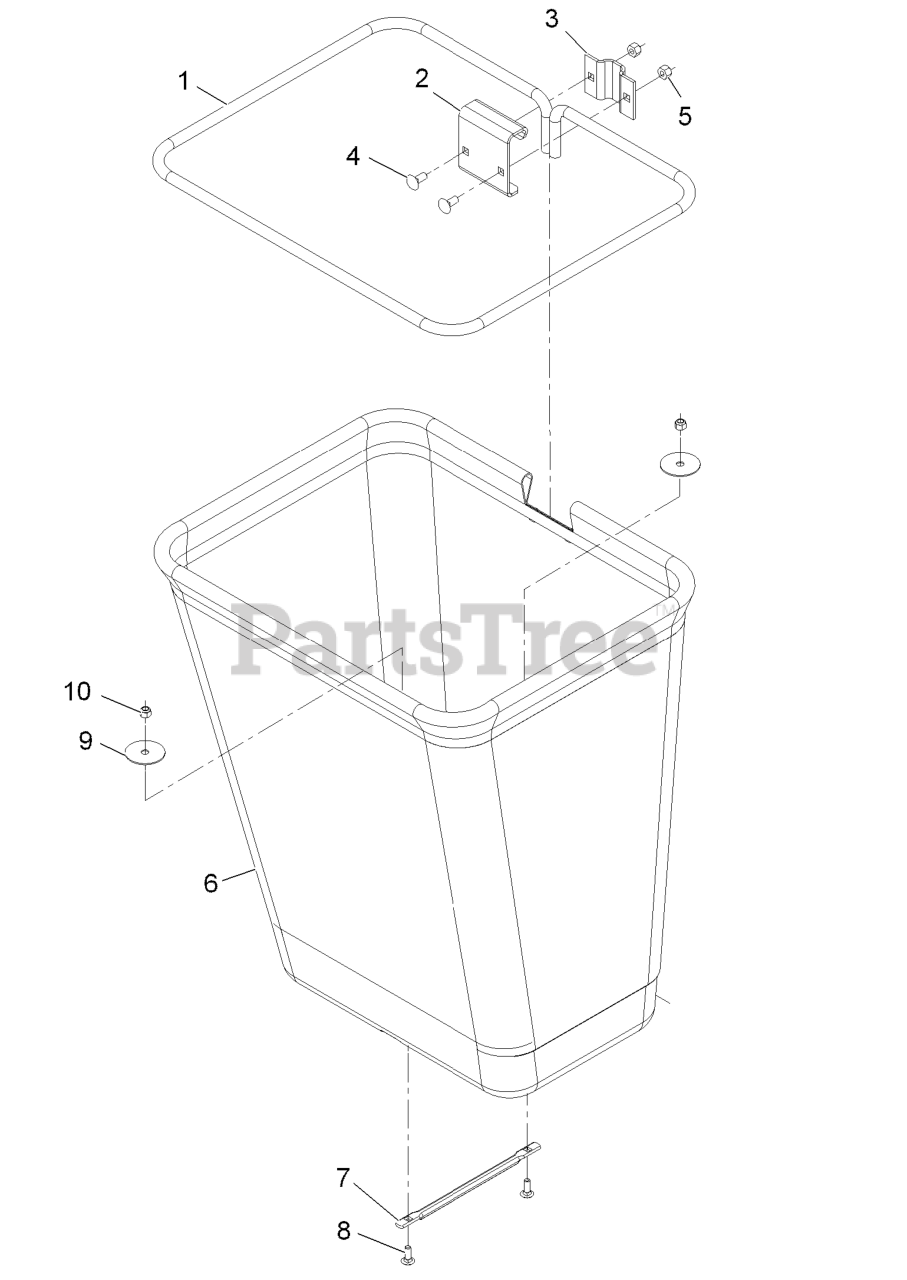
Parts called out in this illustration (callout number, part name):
1	Frame-Bag
2	Hanger-Bag
4	Bolt-Carriage 5/16-18 X 3/4
5	Nut-Nyloc 5/16-18
6	Bag ASM
7	Handle-Bag
8	Bolt-Carriage 1/4-20 X 3/4
10	Nut-Nyloc 1/4-20
